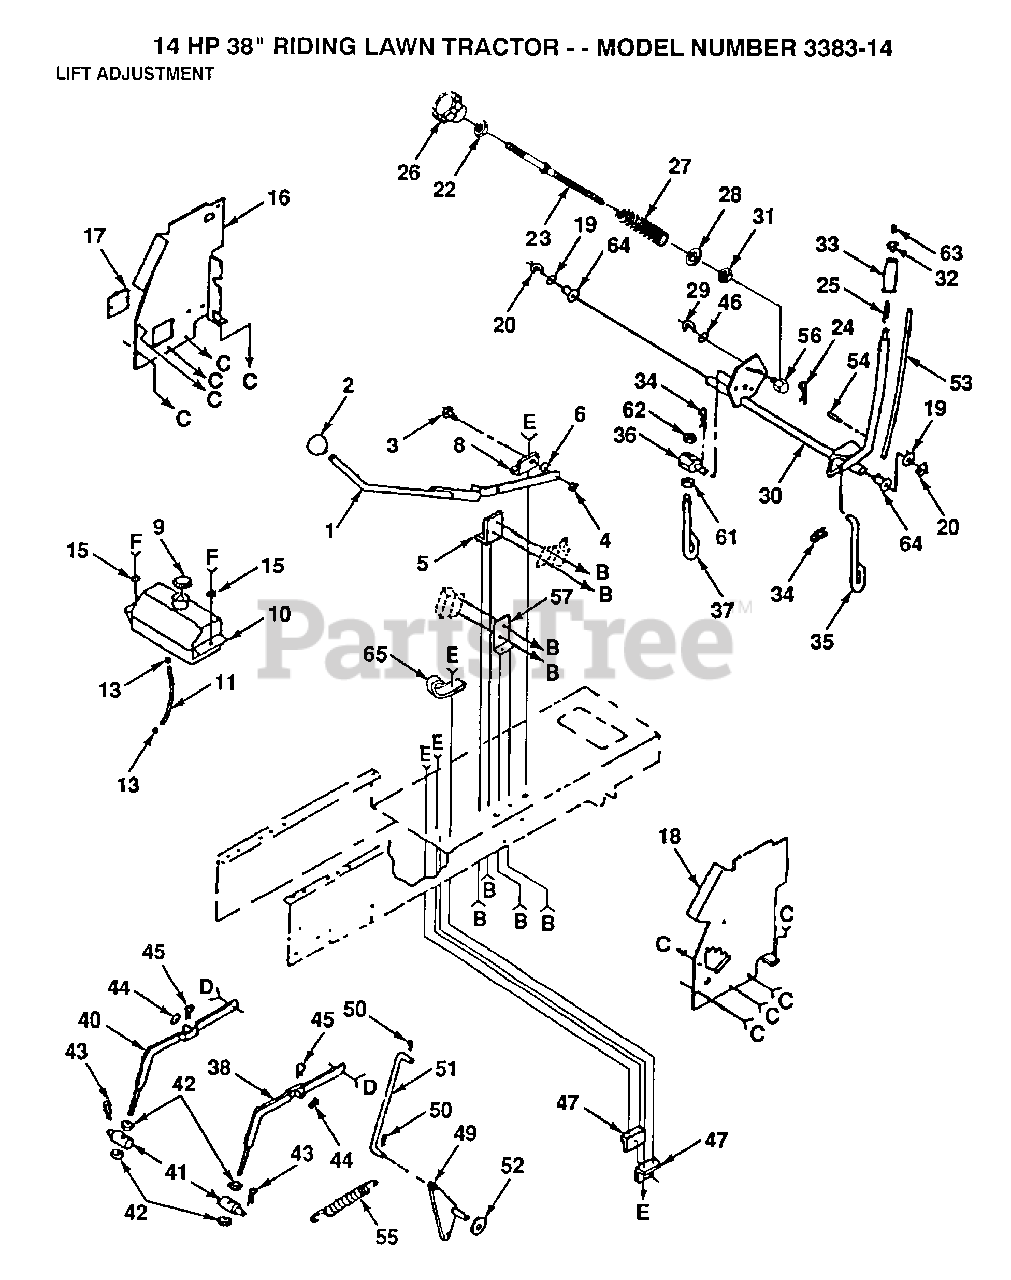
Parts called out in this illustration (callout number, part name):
3	"BOLT, SHOULDER LT"
5	"BRACKET,SWITCH LT"
8	"SUP,LVR,CLUTCH LT"
10	TANK.FUEL.LT.
13	HOSE CLAMP
15	WASHER
16	PANEL DASH LH
17	"BLADE.50""STD.LIFT"
19	WASHER
21	SCREW HEX CRT
22	NUT
26	HDLE ADJ LIFT
27	SPRING T
28	WASHER
29	KLIP RING
31	NUT T
33	GRIP
37	PIVOT PIN T
38	RH SUSP ARM ASM
40	LH SUSP ARM ASM
42	NUT
43	SPRING H
45	SPRING.RETAINER
46	WASHER
47	"BRKT,BELLCRAN T"
49	"T, BELLCRANK"
50	COTTER PIN
52	WASHER
54	PIN-GROOVE LT
56	TRUNION LT
57	BRACKET LT
61	NUT
64	NYLON BEARING
65	INSUL CLIP T
